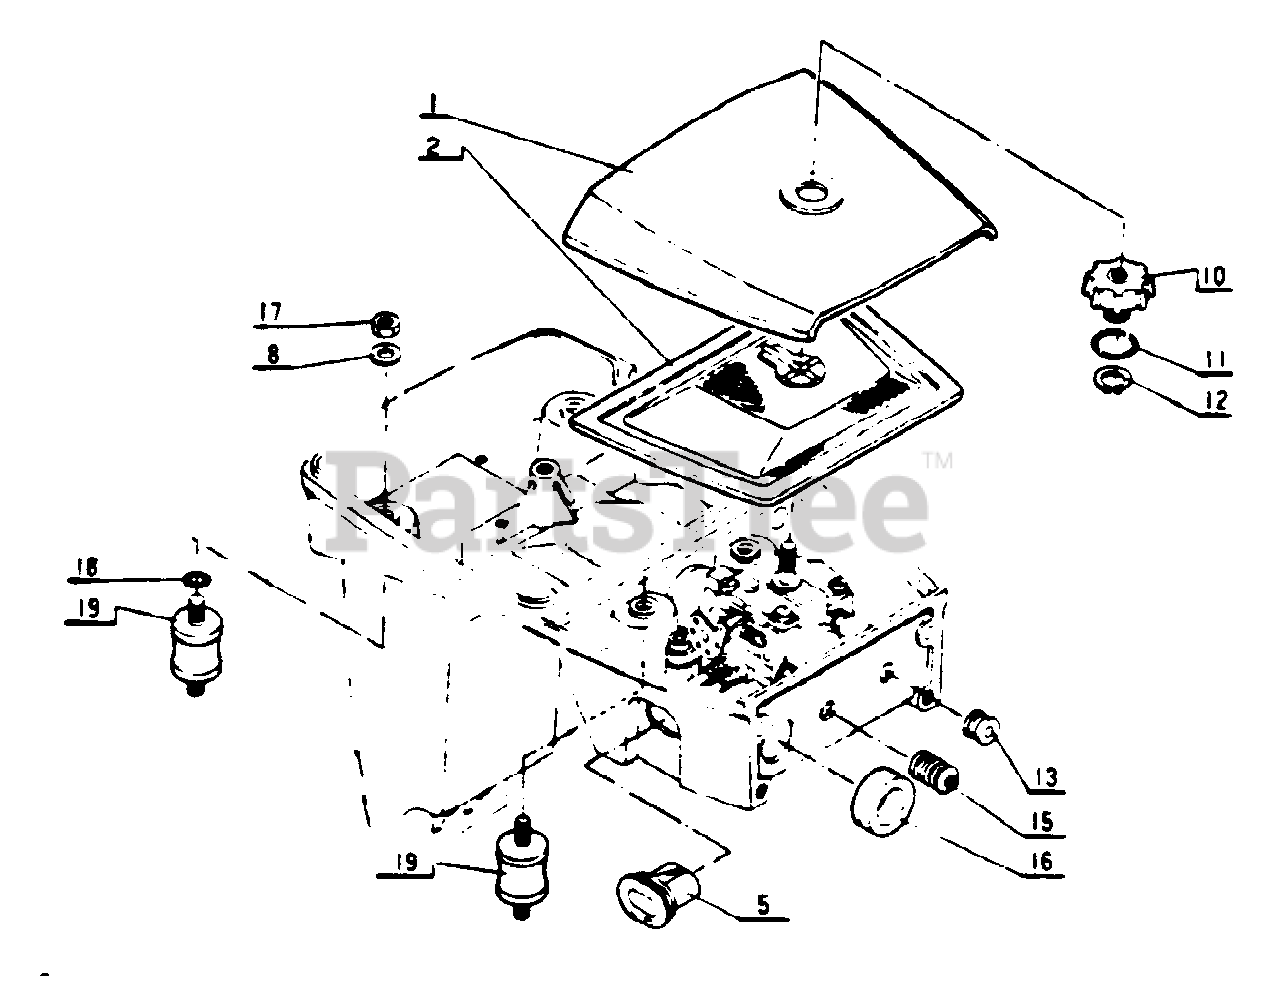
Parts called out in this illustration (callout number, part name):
1	COVER, AIR FILTER
2	FILTER, AIR
8	WASHER 6.5×11.5×0.8
11	O-RING
12	RING, RETAINING
13	GROMMET, RUBBER
16	SEAL, DUST
17	LOCKNUT - 6
18	O-RING
19	CUSHION, RUBBER
